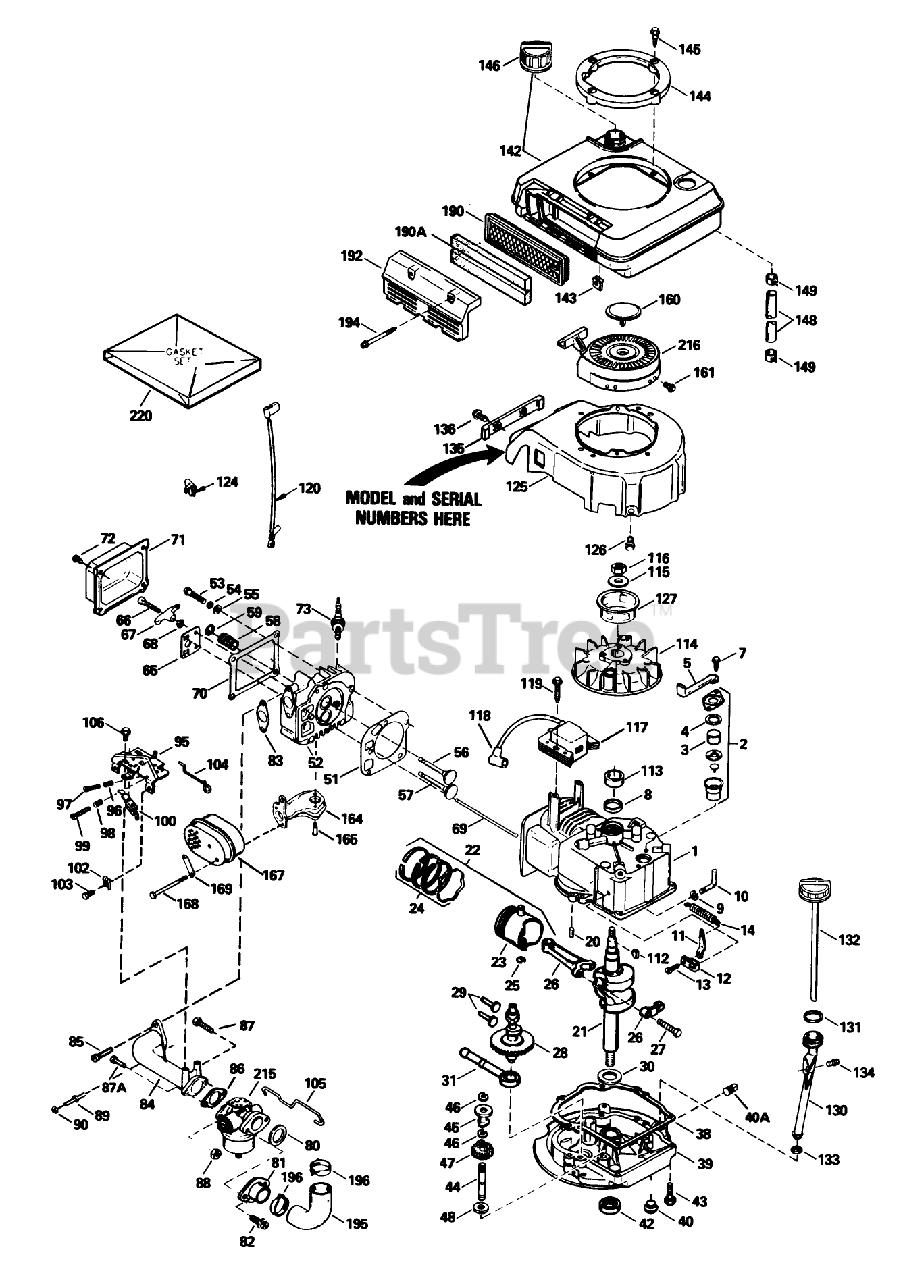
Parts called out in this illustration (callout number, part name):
1	Cylinder Assembly (Incl. Ref. #8 20)
2	Breather Assy. (Incl. Ref. #46 thru 51)
3	Element-Breather
4	Gasket-Breather
5	Tube-Breather
7	Screw (10-24 x 9/16)
8	Seal-Oil
9	Washer-Flat
10	Rod, Governor (Incl. No. 36)
11	Governor Lever
12	Clamp-Lever, Governor
13	Screw
14	Spring-Extension
20	Pin-Dowel
21	Crankshaft
22	Piston-Pin Ring Assy. (Std.)(Incl. Ref. #14A, 15 16)
23	Piston Pin Assy. (Std)(Incl. Ref. #16)
24	Piston Ring Set Std.
25	Ring-Retaining, Piston Pin
26	Rod Assy., Connecting (Incl. Ref. #17)
27	Bolt-Rod, Connecting
28	Camshaft
29	Valve Lifter
30	Washer-Thrust
31	Oil Pump ASM
38	Gasket
39	Flange-Mounting (Incl. Ref. #26, 27 39)
40	Plug Oil Drain
40A	Plug-Pipe
42	Seal-Oil
43	Screw (1/4-20 x 1-1/4)
44	Shaft-Governor
45	Spool-Governor
46	Ring-Retaining
47	Governor Gear ASM
48	Washer
51	Gasket-Cylinder Head
52	Head-Cylinder
53	Screw (5/16-18 x 1-1/2)
54	Washer-Flat
55	Washer-Belleville
56	Valve-Intake Std. (Incl. Ref. #59)
57	Valve-Exhaust Std. (Incl. Ref. #59)
58	Spring-Valve
59	Cap-Valve, Spring
65	Guide-Push Rod
66	Stud-Arm, Rocker
67	Arm-Rocker
68	Nut (1/4-28)
69	Rod-Push
70	Gasket-Cover, Rocker Arm
71	Cover-Rocker Arm
72	Screw
73	Spark Plug-Resistor (R N 4C)
80	Gasket-Air Cleaner
81	Adapter-Air Cleaner
82	Screw-Round Hd.
83	Gasket-Intake Pipe
84	Pipe-Intake
85	Screw-Hex. Hd.
86	Gasket
87A	Screw-Special Hex. Hd.
88	Nut and Lock Washer (1/4-28)
89	Stud-Manifold
90	Nut and Lock Washer (1/4-28)
95	Control Assy.-Remote Speed (Incl. Ref. #69 thru 72 76)
96	61709/GIL1515A/95-5
97	Screw
98	Spring-Compression
99	Screw
100	Terminal
102	Conduit
103	Screw (10-32 x 3/8)
104	2035A67 ADD.ASSEMBL
105	Link-Throttle
106	Screw (10-24 x 9/16)
112	Key-Flywheel
113	Spacer
114	Flywheel
115	Washer-Belleville
116	Nut-Flywheel
117	Solid State
118	Cover-Spark Plug
119	Screw
120	Wire-Ground
124	Clip-Wire
125	Housing-Blower
126	Screw (1/4-20 x 1/2)
127	Hub-Starter
130	Tube-Oil Fill
131	O-Ring
132	Dipstick-Oil Fill
133	Gasket
134	Screw (10-32 x 1/2)
135	Cover-Blower Housing
136	Screw (10-32 x 1/2)
142	Shroud Tank Assembly (Incl. Ref. #143 146)
143	Clip-U-Nut
144	Ring-Shroud
145	Screw
146	Cap-Fuel
148	Line-Fuel
149	Clamp-Fuel Line
160	Plug Starter
161	Screw, Hex Hd.
164	Exhaust Manifold Assembly
165	Screw-Torx Hd. Shoulder
167	Muffler Assembly
168	Screw (5/16-18 X 2-1/2)
169	62513 SNWTHWR W/284
190	Filter-Air Cleaner
190A	Filter-Pre-Cleaner
192	Cover-Air Cleaner
194	Screw-Filester Hd.
195	Tube-Air Cleaner
196	Clamp-Air Cleaner
215	Carburetor Assembly (Incl. Ref. #86)
216	Starter-Rewind
220	Gasket Set
